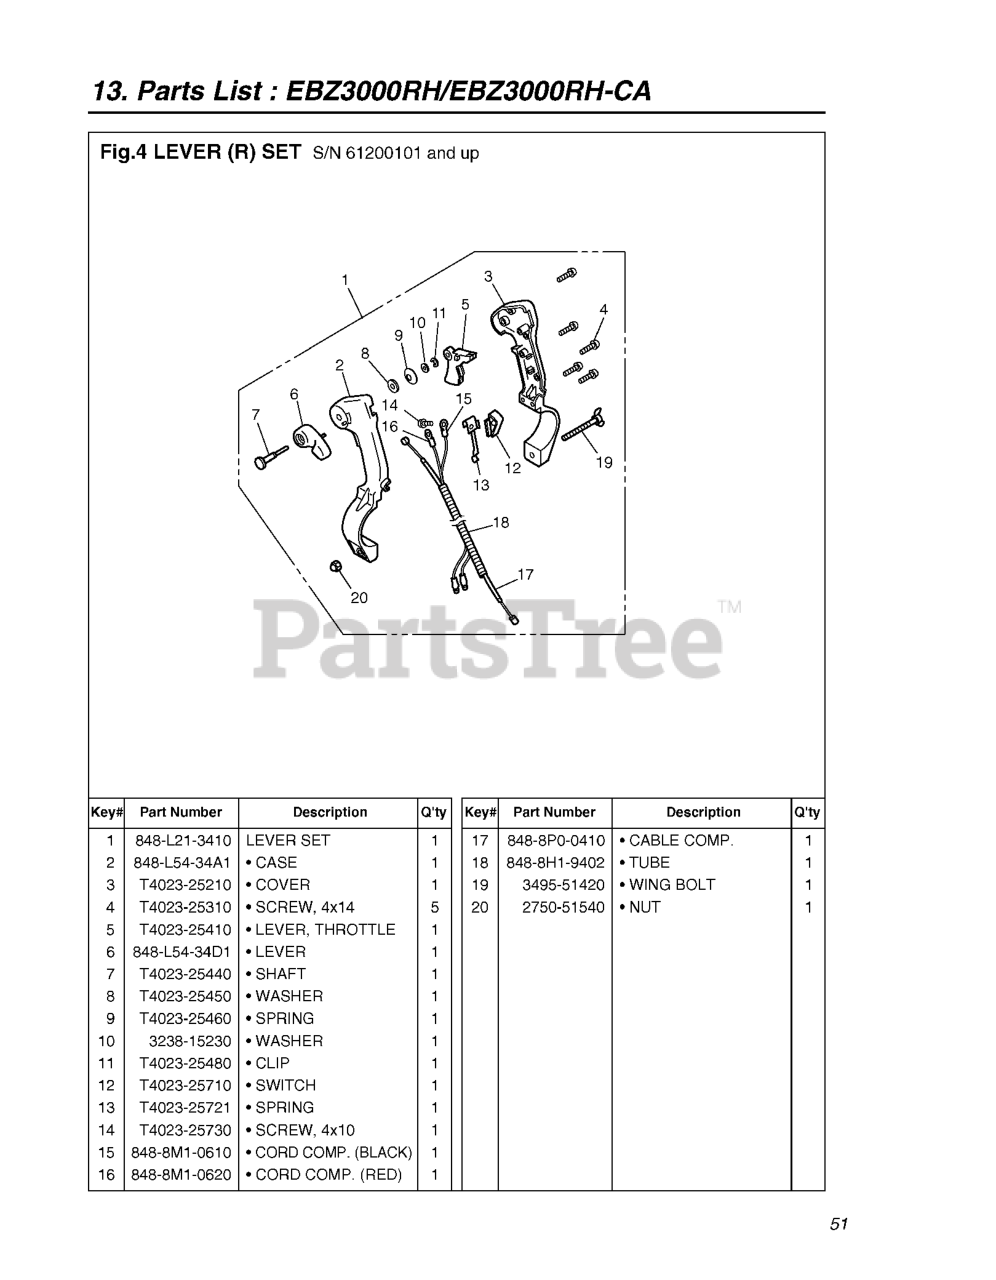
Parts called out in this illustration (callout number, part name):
1	LEVER SET
2	CASE
4	SCREW 4X14(T)
5	LEVER THROTTLE
6	RP_LEVER (RPLS T402325430)
7	SHAFT
8	WASHER(T)
9	RP_SPRING WASHER
10	WASHER
11	RP_CLIP(T)
12	SWTICH (T)
13	SPRING (RPLS T402325720)
14	RP_SCREW 4X10(T)
15	CORD-COMP
16	CORD-COMP
18	TUBE (RPLS T402383210)
19	BOLT WING
